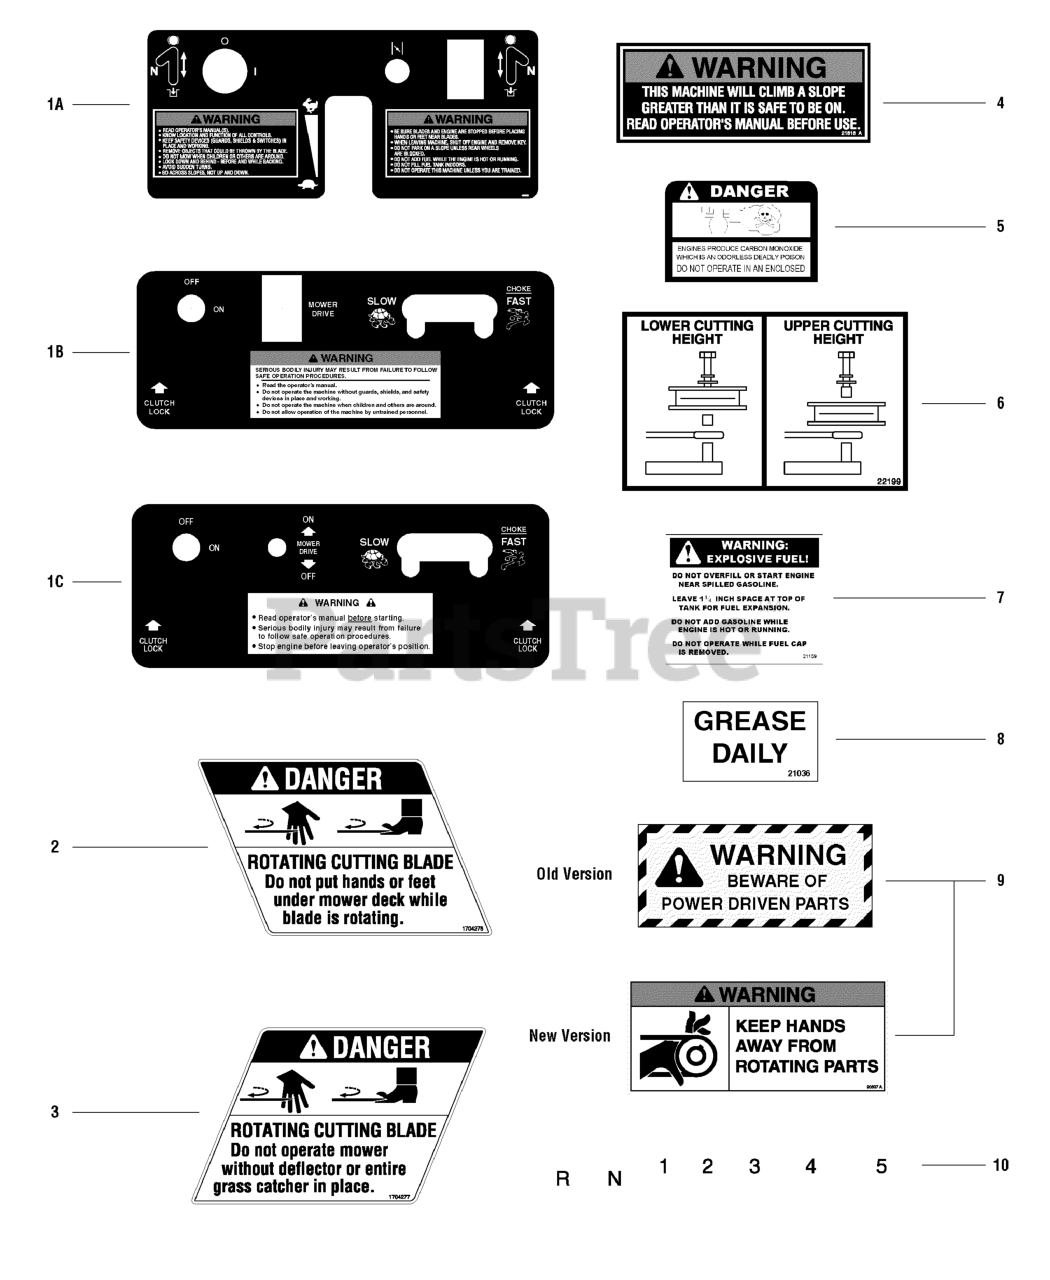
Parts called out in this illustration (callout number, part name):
1A	DECAL, BGF Dash
1B	DECAL, BGF Dash
1C	DECAL, BGF Dash
2	DECAL, Danger (Chute In Place)
3	DECAL, Danger (Hand Under Deck)
4	DECAL, Warning, Machine Will Climb
5	DECAL, Danger, Carbon Monoxide
6	DECAL, Pulley Position
7	DECAL, EXPLOSIVE FUEL
8	DECAL, Grease Daily
9	DECAL, Warning
10	DECAL, Gear Selector
